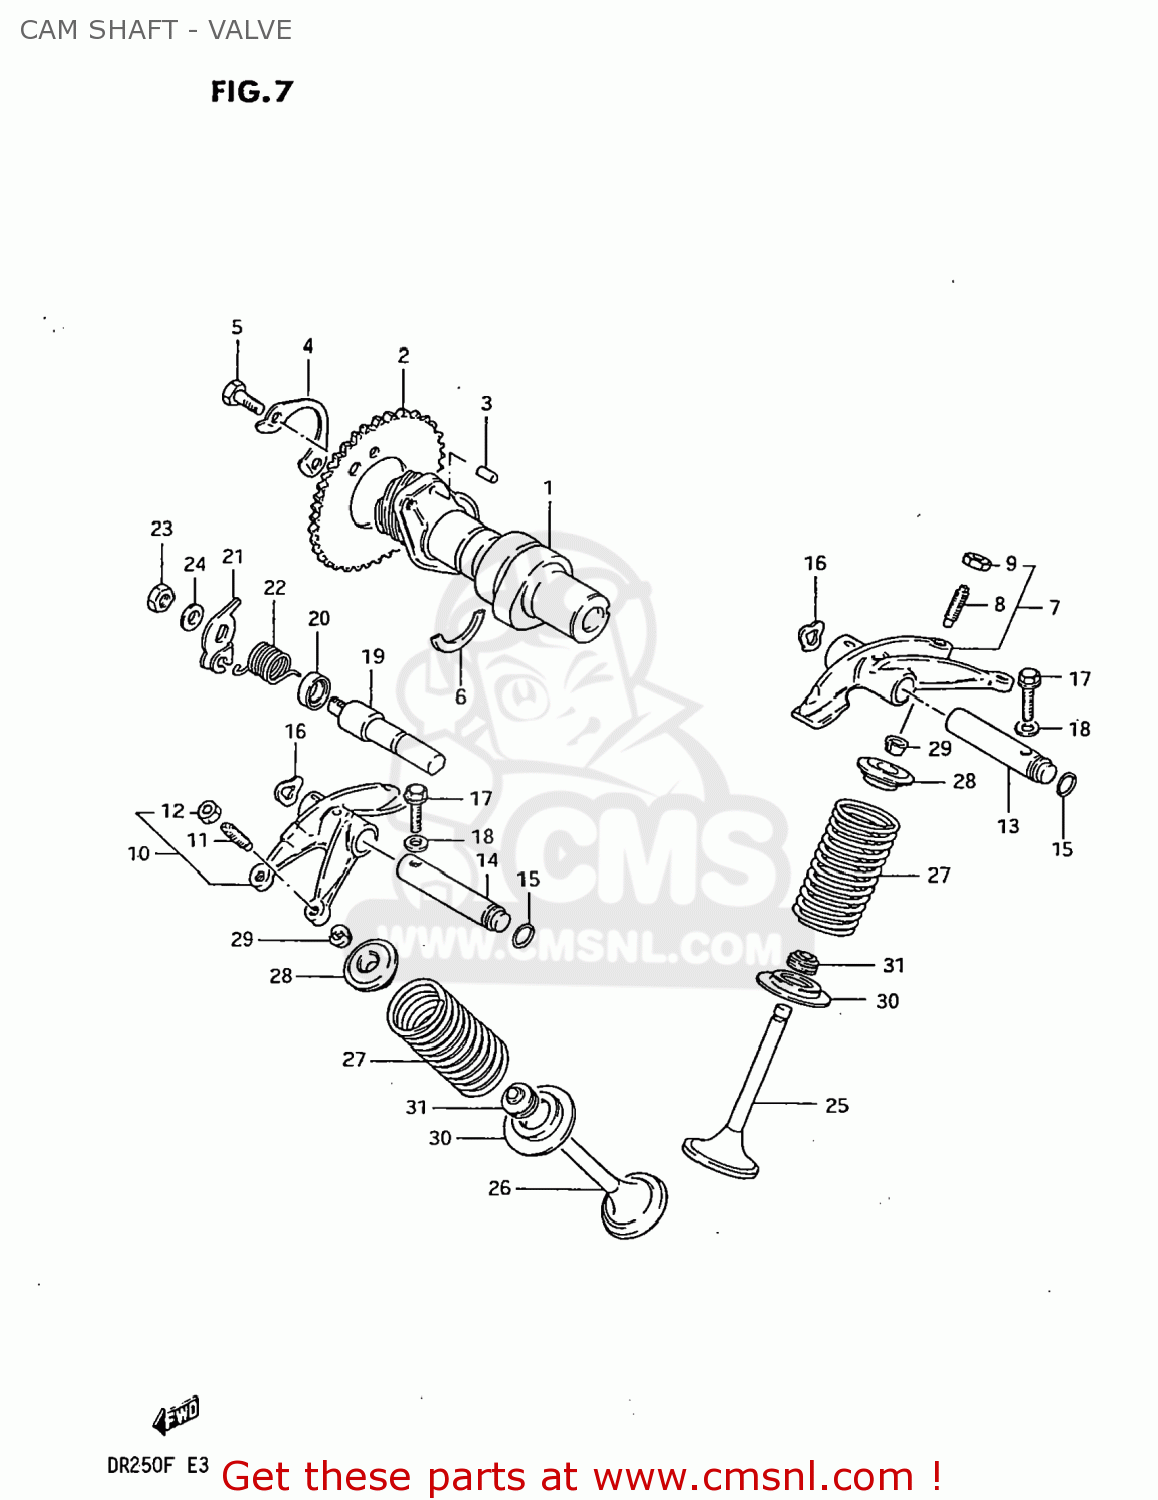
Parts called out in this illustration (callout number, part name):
1	CAMSHAFT
2	SPROCKET,CAMSHAFT(NT:42)
3	PIN
4	WASHER,CAM CHAIN SPROCKET
5	BOLT(6X12.5)
6	C RING
7	ARM,VALVE ROCKER
8	SCREW,TAPPET ADJUSTING
9	NUT,ADJUSTING
10	ARM,VALVE ROCKER,EXHAUST
11	SCREW,TAPPET ADJUSTING
12	NUT,ADJUSTING
13	SHAFT,VLV ROCKER ARM IN(L:91.5
14	SHAFT,VLV ROCKER ARM EXH(L:76)
15	O-RING
16	WASHER
17	BOLT 6X30
18	WASHER
19	SHAFT,DECOMPRESSION
20	OIL SEAL
21	LEVER,DECOMPRESSION SHAFT
22	SPRING
23	NUT 8MM
24	WASHER
25	VALVE,INTAKE
26	VALVE,EXHAUST
27	SPRING,VALVE
28	RETAINER,VALVE SPRING
29	COTTER VALVE
30	SEAT,VALVE SPRING
31	OIL SEAL
